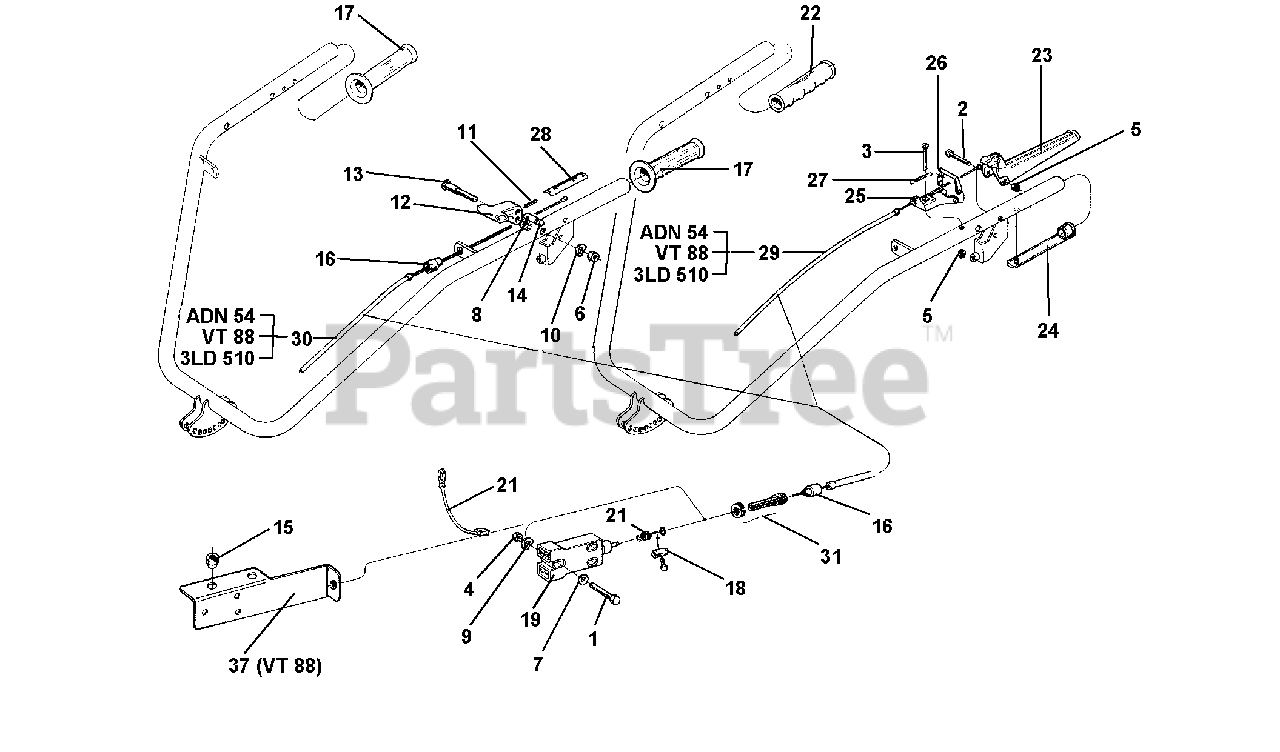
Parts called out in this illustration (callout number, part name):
1	SCREW TE M4 X 25
2	SCREW TE M6 X 45
3	SCREW TSV M6 X 40
5	NUT, SELF LOCKING M6
6	NUT, SELF LOCKING M8
7	FLAT WASHER 4.3
8	WASHER, FLAT 8.4
9	LOCK WASHER B 4.3
10	WASHER, LOCK 8.4
11	PIN, LOCKING 4 X 20
12	LOCKING LEVER
14	DRILLED PIN
16	END, SHEATH
17	KNOB RUBBER HOLE D 25
18	CABLE CLAMP
19	STOP SWITCH
20	SWITCH SPRING
21	SWITCH CABLES
23	MOVABLE MOTOR STOP BODY
25	SHEATH LOCK
26	MOVABLE BODY LOCK
28	RUN-STOP LABEL
29	SHEATH CABLE
30	SHEATH CABLE
31	ADJUSTING SCREW
